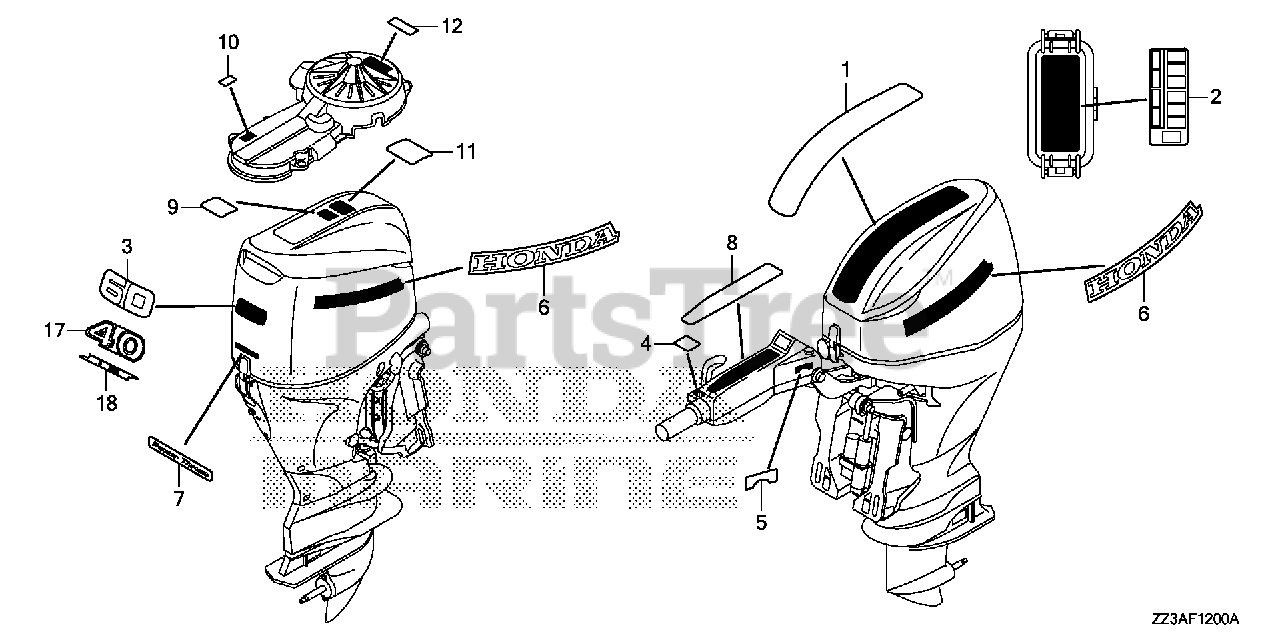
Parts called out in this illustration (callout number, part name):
1	MARK, TOP EMBLEM (60)
2	LABEL, FUSE
3	MARK, RR. (60)
6	MARK, SIDE STRIPE
10	LABEL, OIL CAUTION
11	LABEL, WARNING OPERATOR (ENGLISH)
12	MARK, EMERGENCY START (ENGLISH)
